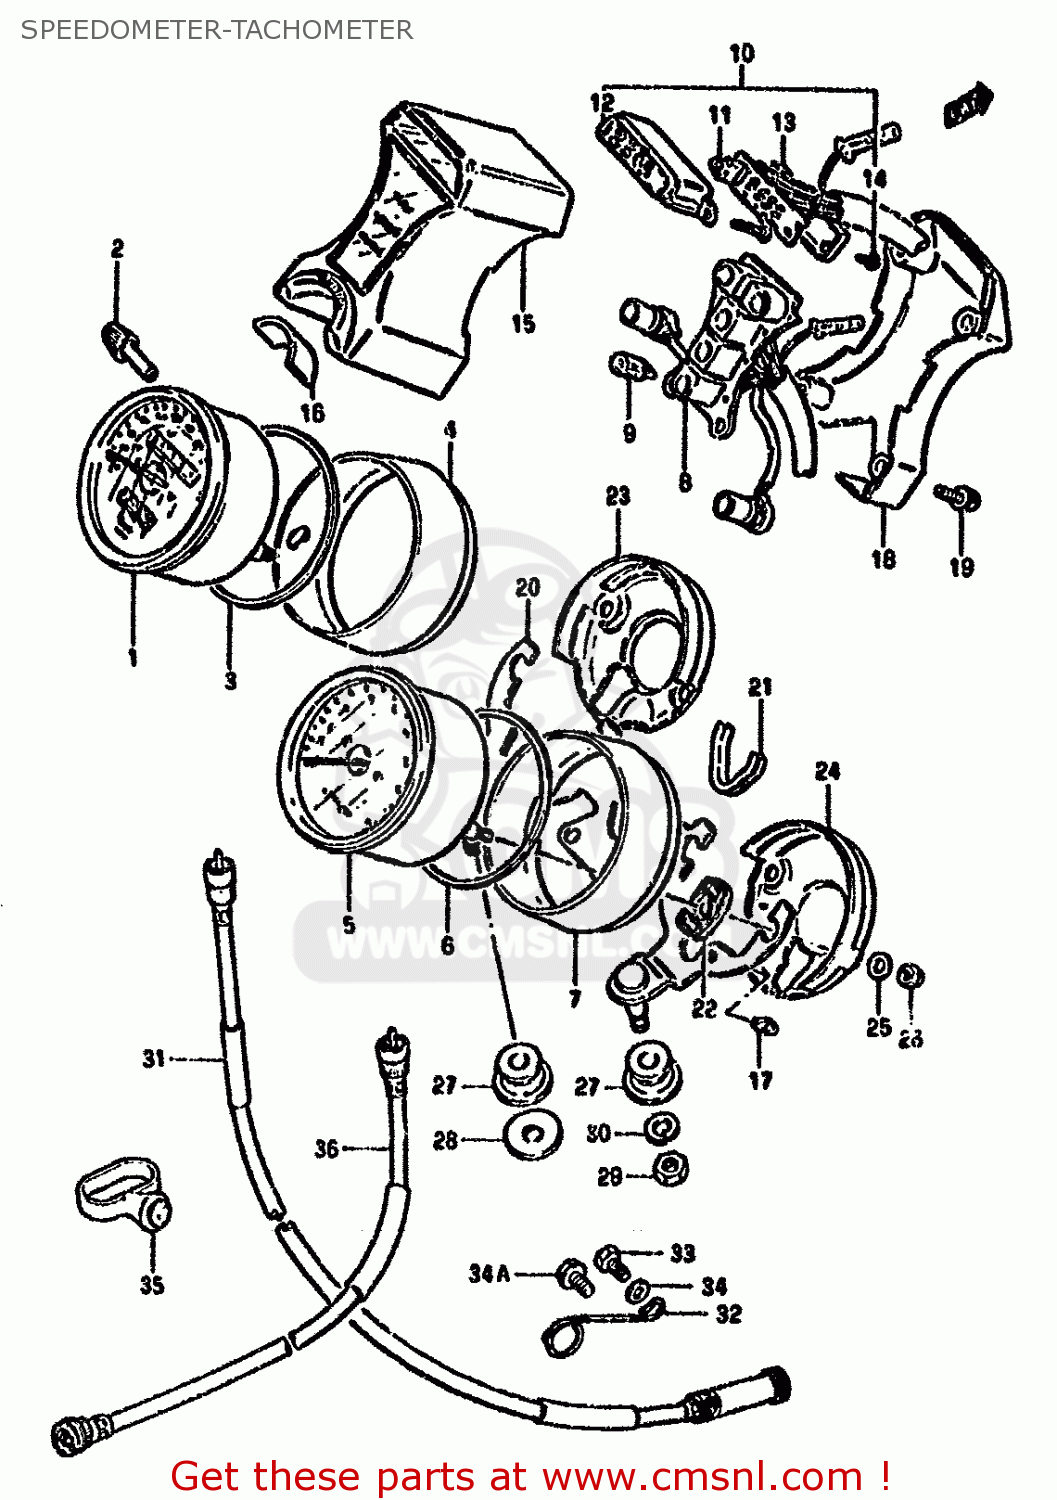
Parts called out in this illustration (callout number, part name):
1	SPEEDOMETER
2	KNOB
3	CUSHION
4	COVER,SPEEDOMETER
5	TACHOMETER ASSY
6	CUSHION
7	COVER,TACHOMETER
8	SOCKET
9	BULB(12V3.4W,T10)
10	INDICATOR ASSY,GEAR POSITION
11	BULB(14V1.12W)
12	CASE,GEAR INDICATOR
13	COVER,LWR
14	SCREW,GEAR INDICATOR
15	BOX,PILOT
16	SEAL,IGNITION SWITCH
17	CUSHION
18	COVER,PILOT BOX LWR
19	SCREW,PILOT BULB CASE
20	BRACKET
21	BRACKET,COVER
22	CUSHION,METER
23	ORNAMENT,SPEEDOMETER
24	COVER,TACHOMETER
25	WASHER
26	NUT
27	CUSHION,METER BRACKET
28	WASHER (8.5X20X1.6)
29	NUT
30	LOCK WASHER
31	CABLE ASSY,SPEEDOMETER
32	CLAMP,SPEEDOMETER CABLE
33	BOLT
34	WASHER
34A	BOLT
35	GUIDE,CABLE
36	CABLE ASSY,TACHOMETER
